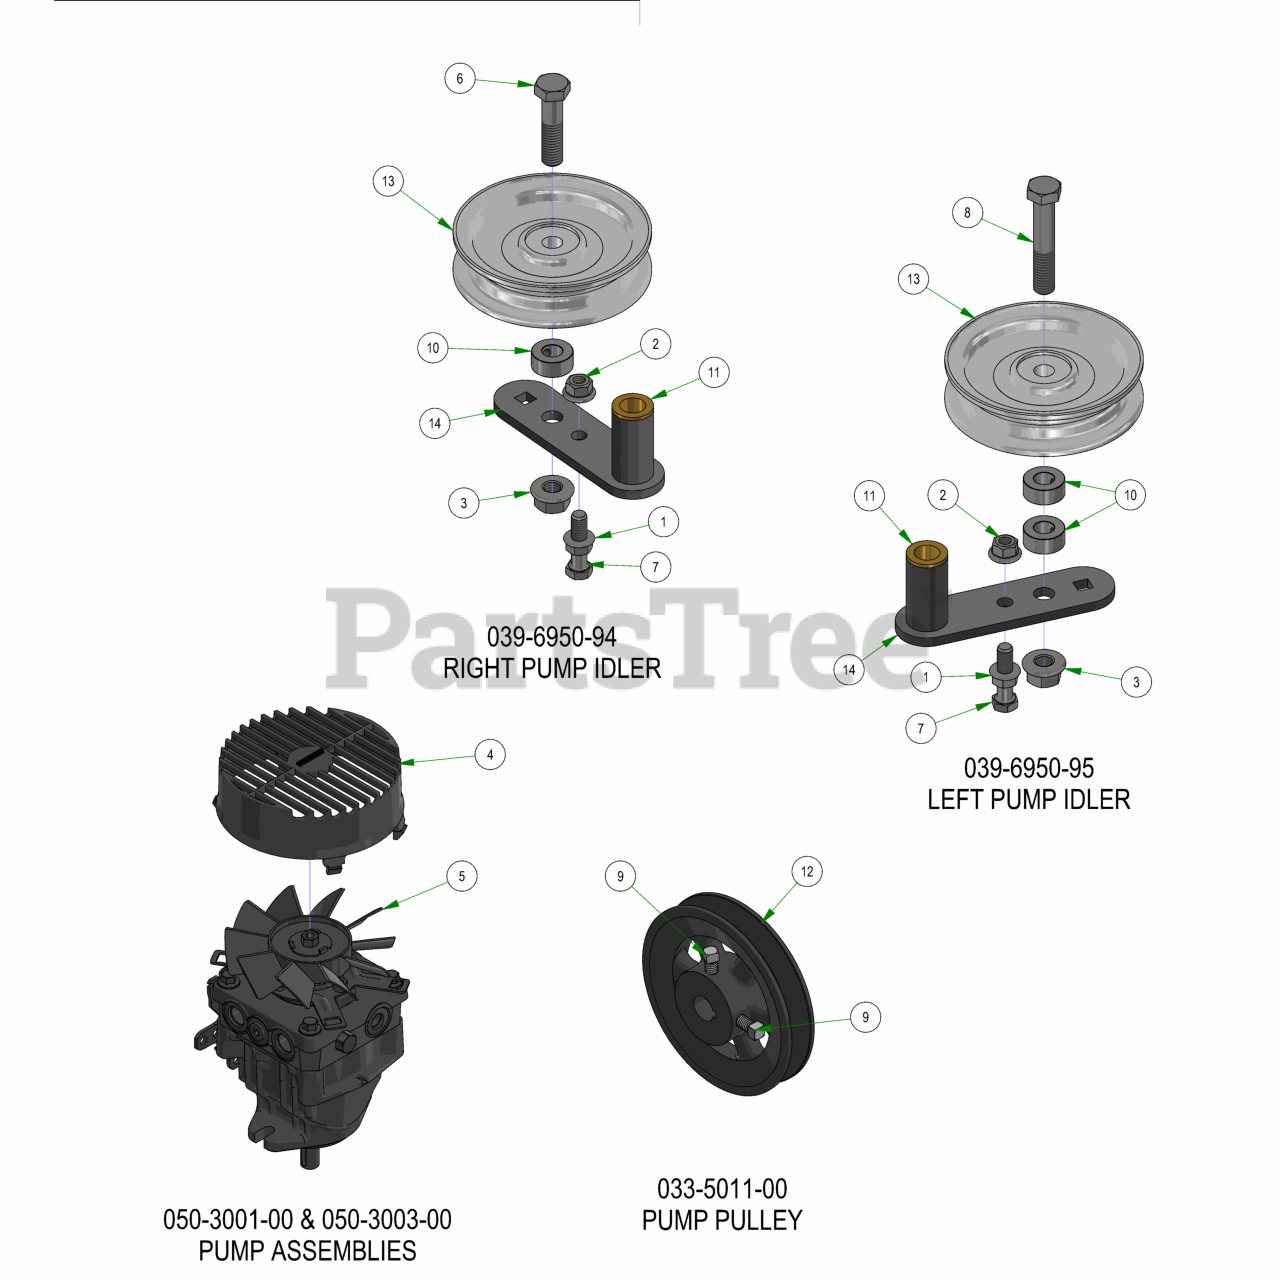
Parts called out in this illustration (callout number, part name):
1	3/8-16 HEX SERRATED FLANGE NUT HARD/ZINC
2	3/8-16 NYLON INSERT FLANGE LOCKNUT (GR.F) ZINC
3	1/2-13 NYLON INSERT FLANGE LOCKNUT ZINC
4	Fan Guard 6" - Fits Wheel
5	Hydro Fan - Light/Pup/Outlaw XP
6	1/2-13 X 2 HEX CAP SCREW (GR.8) ZINC YELLOW
7	3/8-16 X 1-1/2 HEX CAP SCREW (GR.5) ZINC
8	1/2-13 X 2-3/4 HEX CAP SCREW (GR.5) ZINC
9	Square-Head Cup-Point Set Screw 5/16''-18
10	1/2 SOLID SHAFT COLLAR (W/1 SET SCREW) ZINC
11	.627 ID X .753 OD X .500 LGTH X 1.000 FLG OD X .094 FLG THICK FLANGED BEARING OIL-IMPREG BRNZ
12	5" Pump Pulley
13	4 3/4" Idler Pulley
14	Renegade - Gas Pump Idler - Weldment
